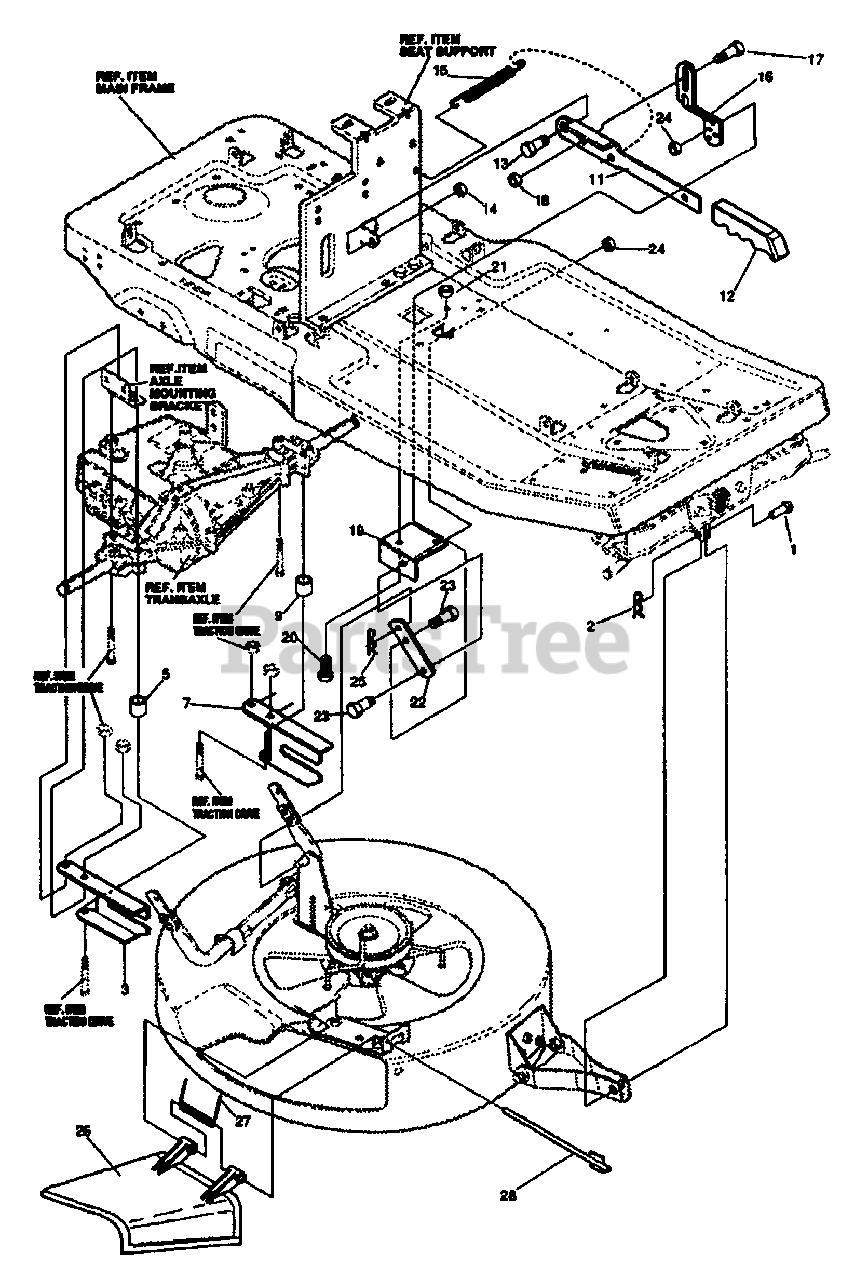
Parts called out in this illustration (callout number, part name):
1	PIN, .495 X 1.750 CLEVIS-SHORT
2	PIN, HAIR .091 DIA X 1.62LG
3	BRACKET, REAR SUPPORT RH
5	SPACER .328 X .750 X .312
7	BRACKET, REAR SUPPORT LH
9	SPACE .320 X .750 X .312
11	HANDLE, HEIGHT ADJUST
12	GRIP, HANDLE, LIFT
13	BOLT, .500 X .345 HHSH 3/8-16
14	NUT, 3/8-16 REGHXCTRLK
15	SPRING .071 X .62 X 4.37
16	BRKT, LINK UPPER 30" MOW
17	BOLT, .500 X .345 HHSH 3/8-16
18	NUT, 3/8-16 REGHXCTRLK
19	BRACKET, RER FRAME
20	SCREW, 5/16-18 X .88 HHC
21	NUT, 5/16-18 REGHEXCTRLK
22	BRKT, LINK LOWER 30" MOW
23	BOLT, .500 X .225 HHSH 5/16-18
24	NUT, 5/16-18 REGHEXCTRLK
25	PIN, HAIR .091 DIA X 1.62LG
26	CHUTE DEFLECTOR 30" DECK
27	SPRING TORSION CHUTE DEF.
28	ROD, PIVOT 40" DECK .312 x 7.25
